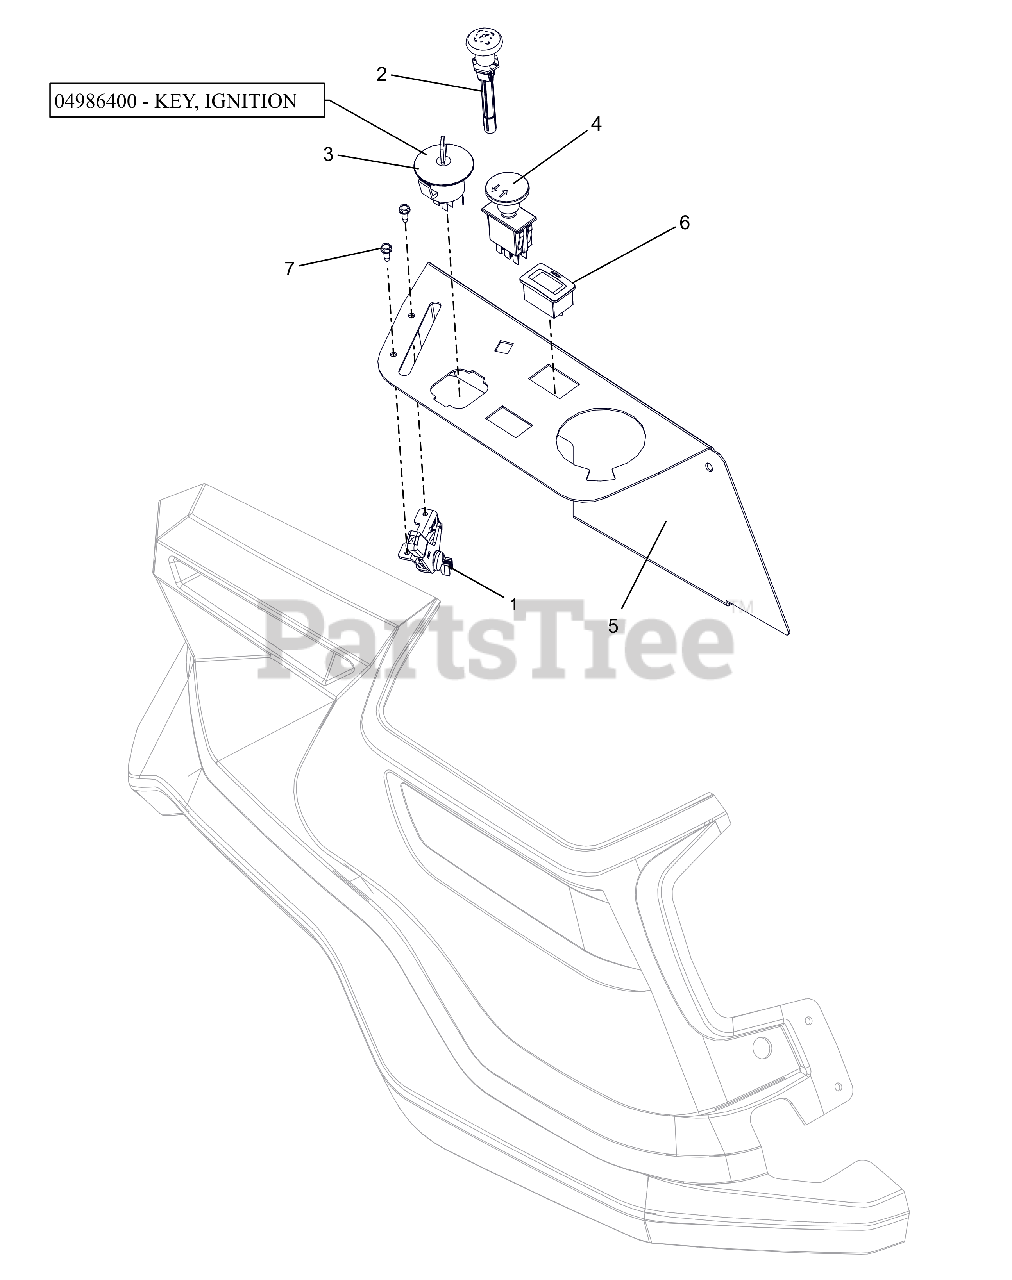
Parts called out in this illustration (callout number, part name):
1	CABLE - THROTTLE CONTROL
2	CABLE - CHOKE, SNAP-IN
3	KEYSWITCH-IGNITION 4 POS
3	KEY, IGNITION
4	SWITCH, CLUTCH (YELLOW)
5	PANEL, RIGHT SIDE FENDER MOUNT
6	HOUR METER
7	SCR,TAP #10-24X.50 HWH TR ZCC
